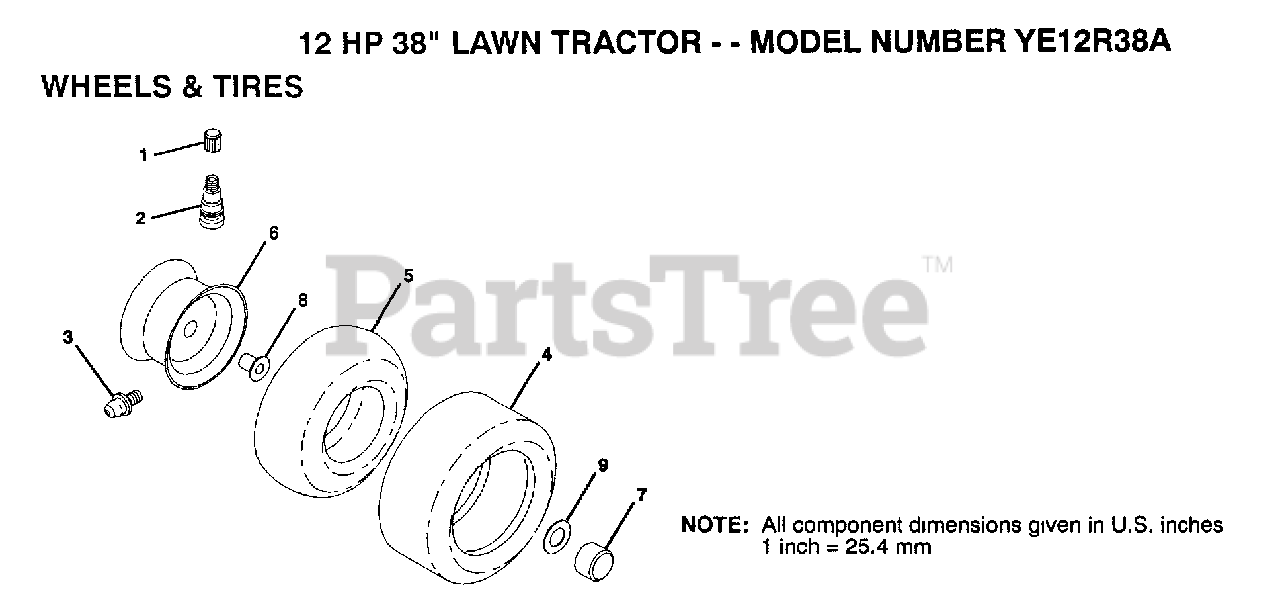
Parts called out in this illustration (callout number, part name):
1	VALVE CAP
2	VALVE STEM LT
3	FITTING LT
5	TUBE.5.3/4.5/6
7	HUB CAP
8	"FLANGE, BEARING"
9	WASHER
